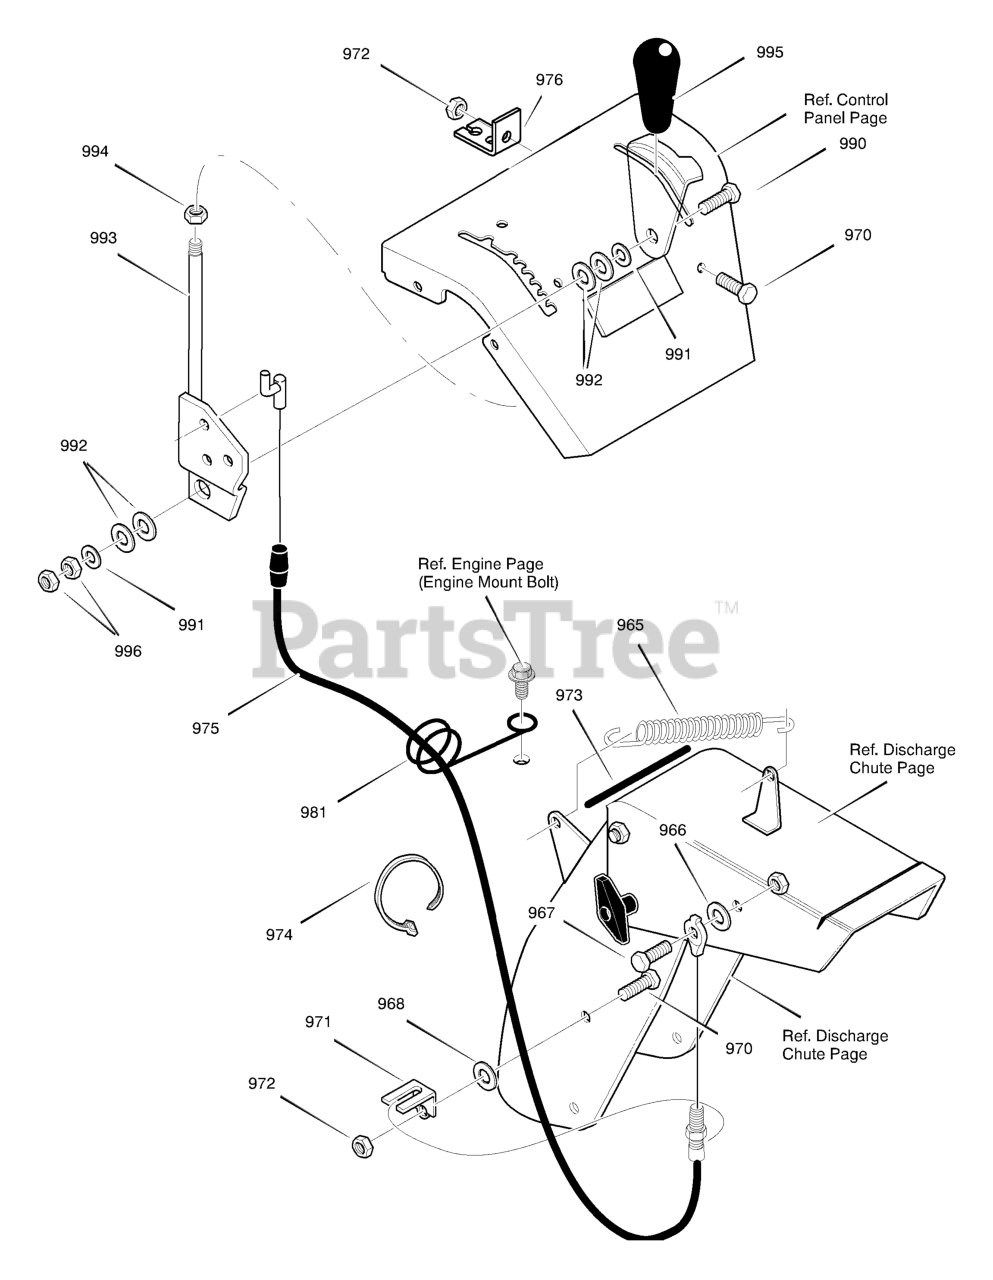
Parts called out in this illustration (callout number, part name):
965	TENSION SPRING
966	FLATWASHER
968	FLATWASHER
971	BRACKET, CABLE CHUTE
972	NUT
973	TRIM STRIP, GREY
974	TIE, CABLE
975	CABLE, CHUTE DEFLECTOR
976	BRACKET, CABLE CHUTE
981	WIRE FORM, REMOTE CHUTE CABLE
985	BRACKET, SNAP-IN REMOTE
990	SCREW
991	WASHER, FLAT
992	WASHER, SPRING
993	HANDLE, ASSY
995	KNOB, SHIFT (GREY)
996	NUT
